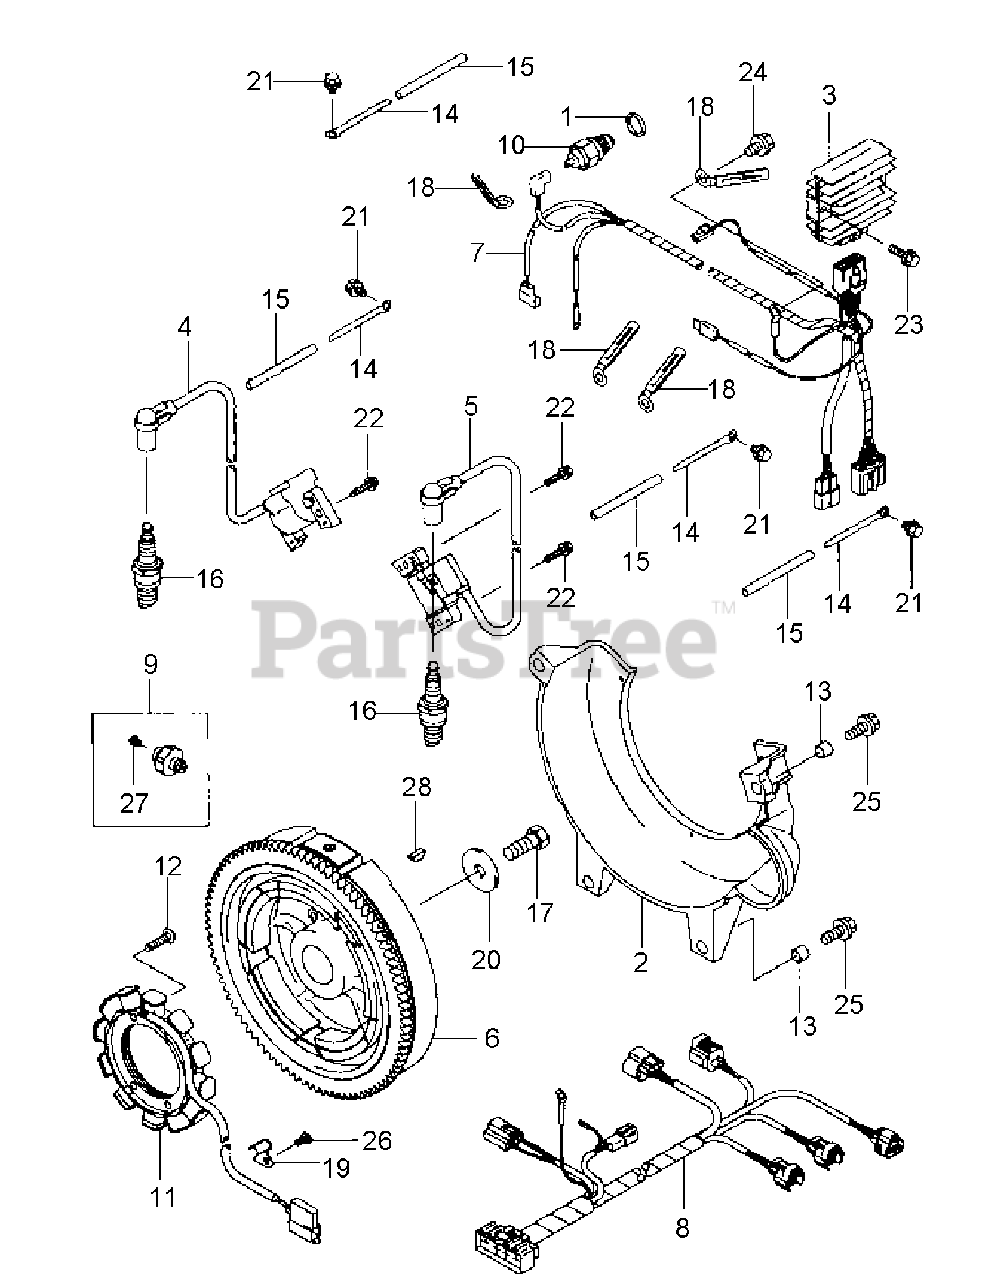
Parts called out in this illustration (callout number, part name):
2	FLYWHEEL COVER
3	VOLTAGE REGULATOR
4	IGNITION COIL #1
5	IGNITION COIL #2
6	FLYWHEEL
9	SWITCH
16	SPARK PLUG
21	FLANGED BOLT
22	FLANGED BOLT
23	FLANGED BOLT
24	FLANGED BOLT
25	FLANGED BOLT
28	WOODRUFF KEY
